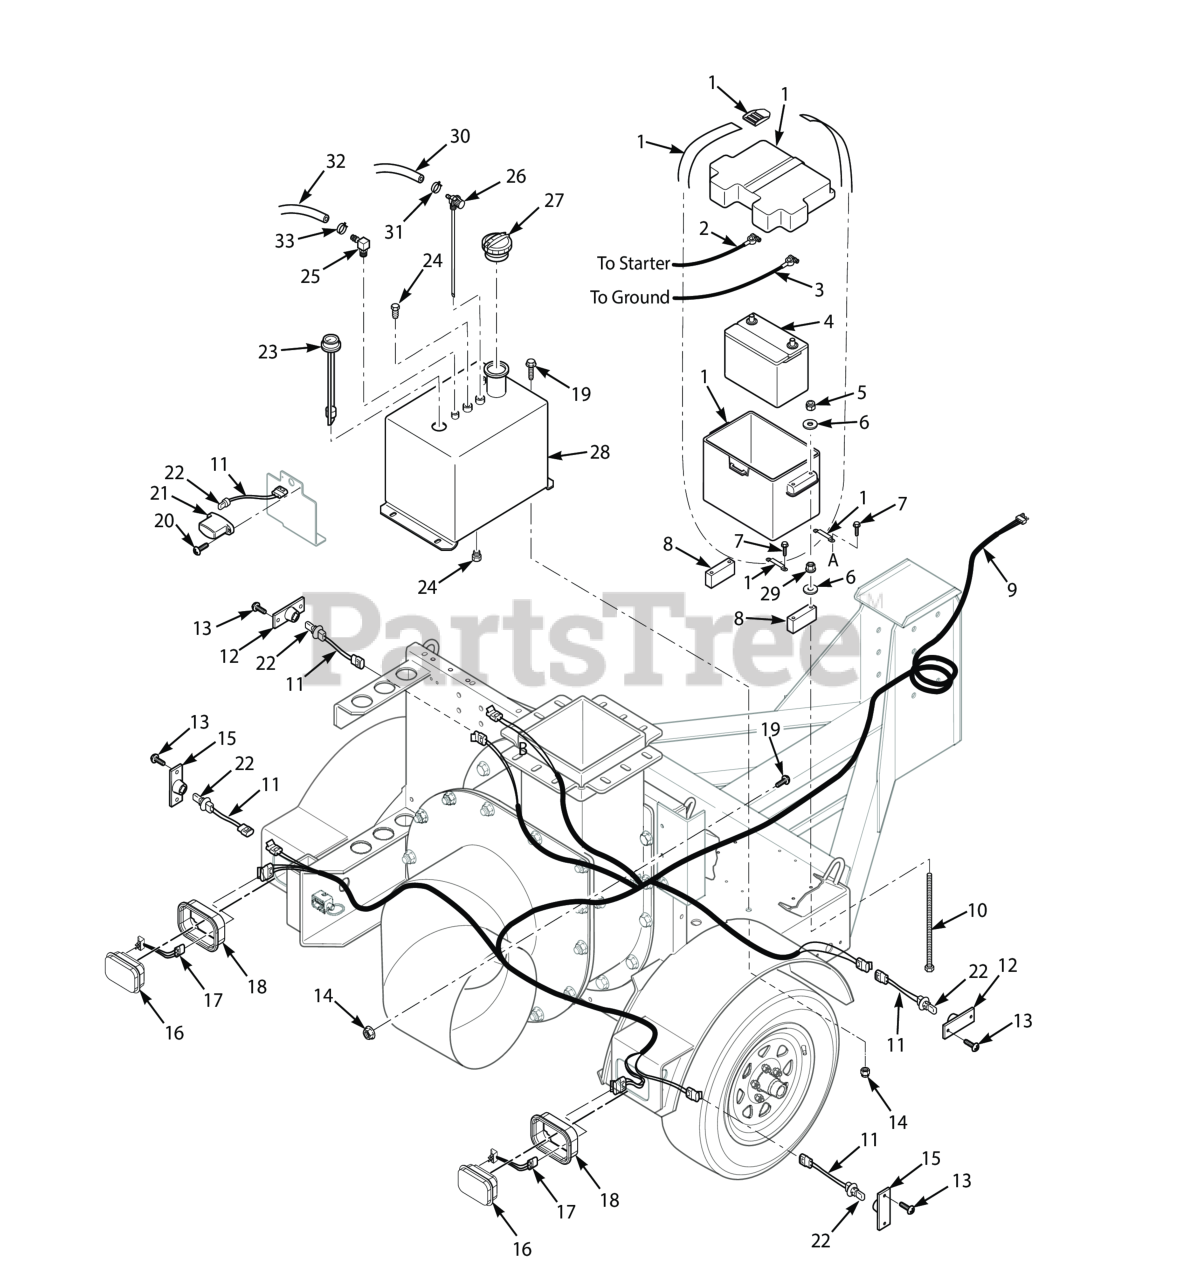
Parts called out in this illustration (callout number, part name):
1	Battery Box, GRP24
2	Cable, Positive Battery
3	Battery Cable, Black
4	Battery (Not Avail. through Scag, Exide P/N 26R)
5	HEX, NUT, ELASTIC STOP LOCK, 1/4-20
6	Flatwasher, 1/4" (.312 x .750 x .065")
7	Screw, #10-32 x .563 Shakeproof
8	Spacer, Battery Bob (x6)
9	Wire Harness, TL
10	Bolt, Carriage 1/4-20 x 7-1/2"
11	Pigtail, Side Marker Light
12	Side Marker Light, Yellow (does not include #42)
13	Screw, #8-18 x 3/4" Self Tap
14	NUT, 3/8-16 SERRATED FLANGE HEX HEAD
15	Side Marker Light, Red (does not include #42)
16	Stop / Turn / Tail Light
17	Pigtail, Tail Light
18	Grommet, Tail Light
19	Bolt, Hex Head Serrated Flange 3/8-16 x 3/4"
20	SCREW, 10-32 X 3/4" SELF TAP
21	Light, License Plate (includes #42)
22	Light Bulb, 194
23	Fuel Gauge Assembly
24	Plug, 1/4" NPT Socket Head
25	Fuel Return Line Fitting
26	Fuel Pick Up Tube
27	Fuel Cap, Steel Tank - Diesel
28	Fuel Tank Assembly (incl. #23, 24, 25, 26, 27)
29	NUT, 1/4-20 SERRATED FLANGE HEX HEAD
30	Fuel Hose, 5/16" I.D. Non-Perm (791DFI) - Order by Inch
31	Clamp, Fuel Hose 5/16" I.D. (791DFI)
32	Hose, 3/16" I.D. (order by inch)
33	Clamp, Fuel Return Hose
